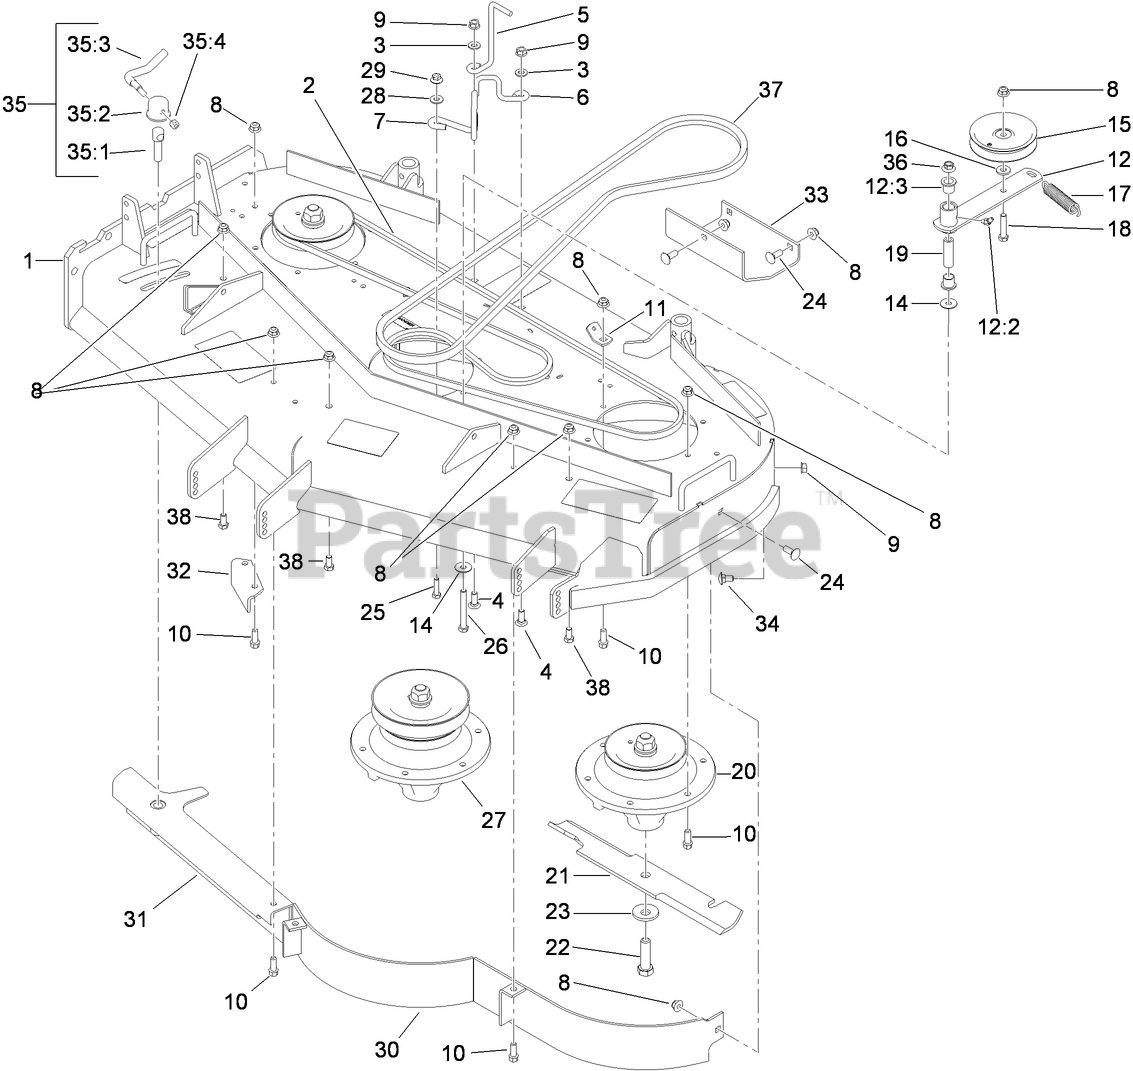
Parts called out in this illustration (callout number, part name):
1	DECK ASM
2	BELT-V
3	WASHER-FLAT
4	SCREW-CARR
5	GUIDE-BELT
6	GUIDE-BELT
7	GUIDE-BELT
8	NUT-HF, NI
9	NUT-HF
10	SCREW-HWH
11	PLATE-SPRING
12	IDLER ARM ASM
12:2	FITTING-LUBE, 45 DEG
12:3	BUSHING-FLANGE
14	WASHER
15	PULLEY-IDLER
16	WASHER-SPACER
17	SPRING-EXTENSION
18	SCREW-HH
19	SPACER
20	SPINDLE ASM
21	BLADE-16.5 INCH (HIGH FLOW)
22	SCREW-BLADE
23	Washer-Blade Bolt, Heavy
24	BOLT-CARR
25	SCREW-HH
26	SCREW-HH
27	SPINDLE ASM
28	WASHER-FLAT
29	NUT-HF
31	ADJUSTABLE BAFFLE ASM
32	BAFFLE-DISCHARGE
34	SCREW-CARR
35	LEVER ASM
35:1	Screw-Lock
35:2	CAP-LOCK
35:3	Lever-Lock
35:4	NUT-LOCK, NI
36	NUT-HF
37	BELT-V
38	SCREW-HH
